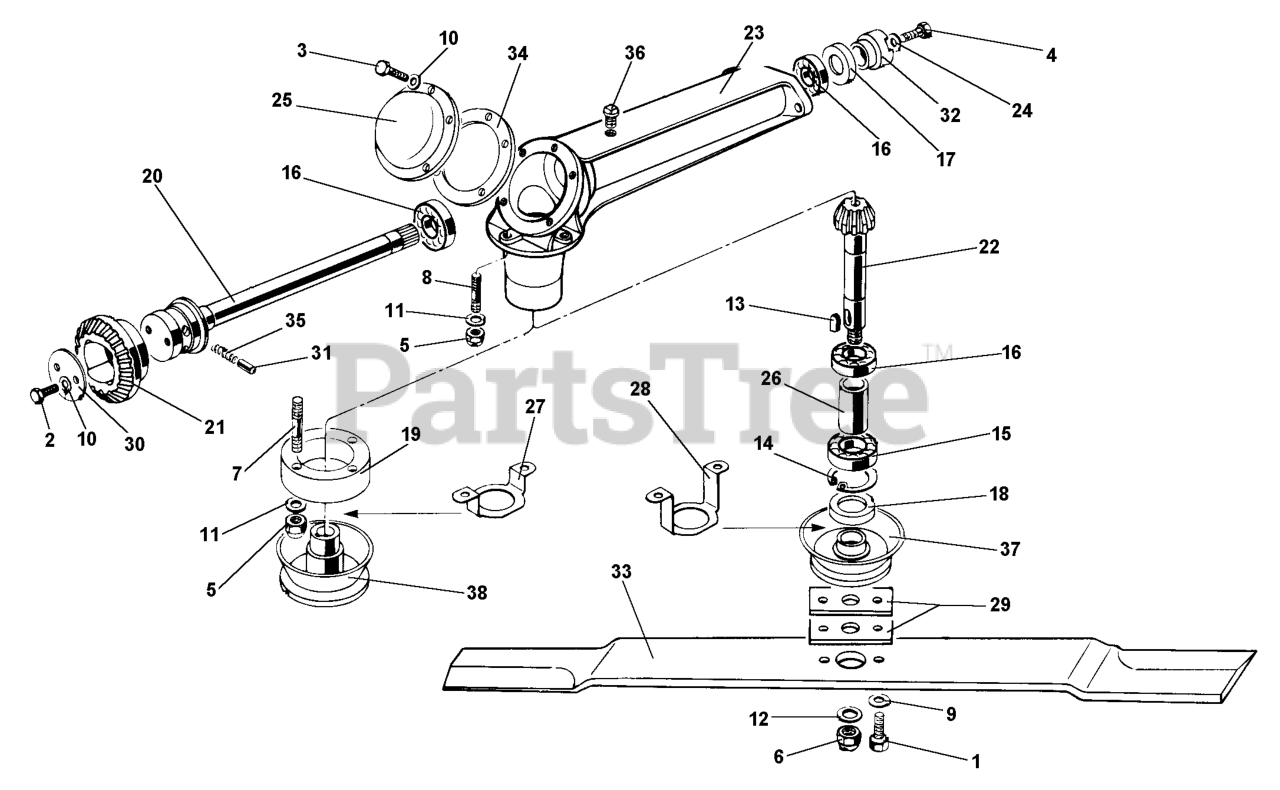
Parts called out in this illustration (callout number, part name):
1	SCREW TE M14 X 50
2	SCREW M6 X 12
3	SCREW TE M6 X 16
4	SCREW TE M6 X 20
5	NUT, SELF LOCKING M8
6	NUT, SELF LOCKING M18 X 1.5
8	STUD M8 X 40 X 14 X 14
9	SUPER WASHER
10	WASHER, LOCK 6.4
11	WASHER, LOCK 8.4
12	WASHER, LOCK
13	KEY, 6 X 6 X 20
14	CIRCLIP, INTERNAL D 62
15	BEARING 25 X 62 X 17 6305
16	BEARING 25 X 52 X 15
17	OIL SEAL 35 X 47 X 7 STANDARD
18	OIL SEAL 40 X 62 X 7
20	SHAFT FOR GEAR
21	RING BEVEL GEAR
22	BEVEL PINION
23	MOWER CASING
24	WASHER 7 X 25 X 4
27	OIL SEAL PROTECTOR
28	OIL SEAL PROTECTOR
29	BLADE SPACER
30	DISC, GEAR LOCKING
36	BREATHER CAP 1/4
37	BLADE HOLDER HUB
38	BLADE HOLDER HUB
